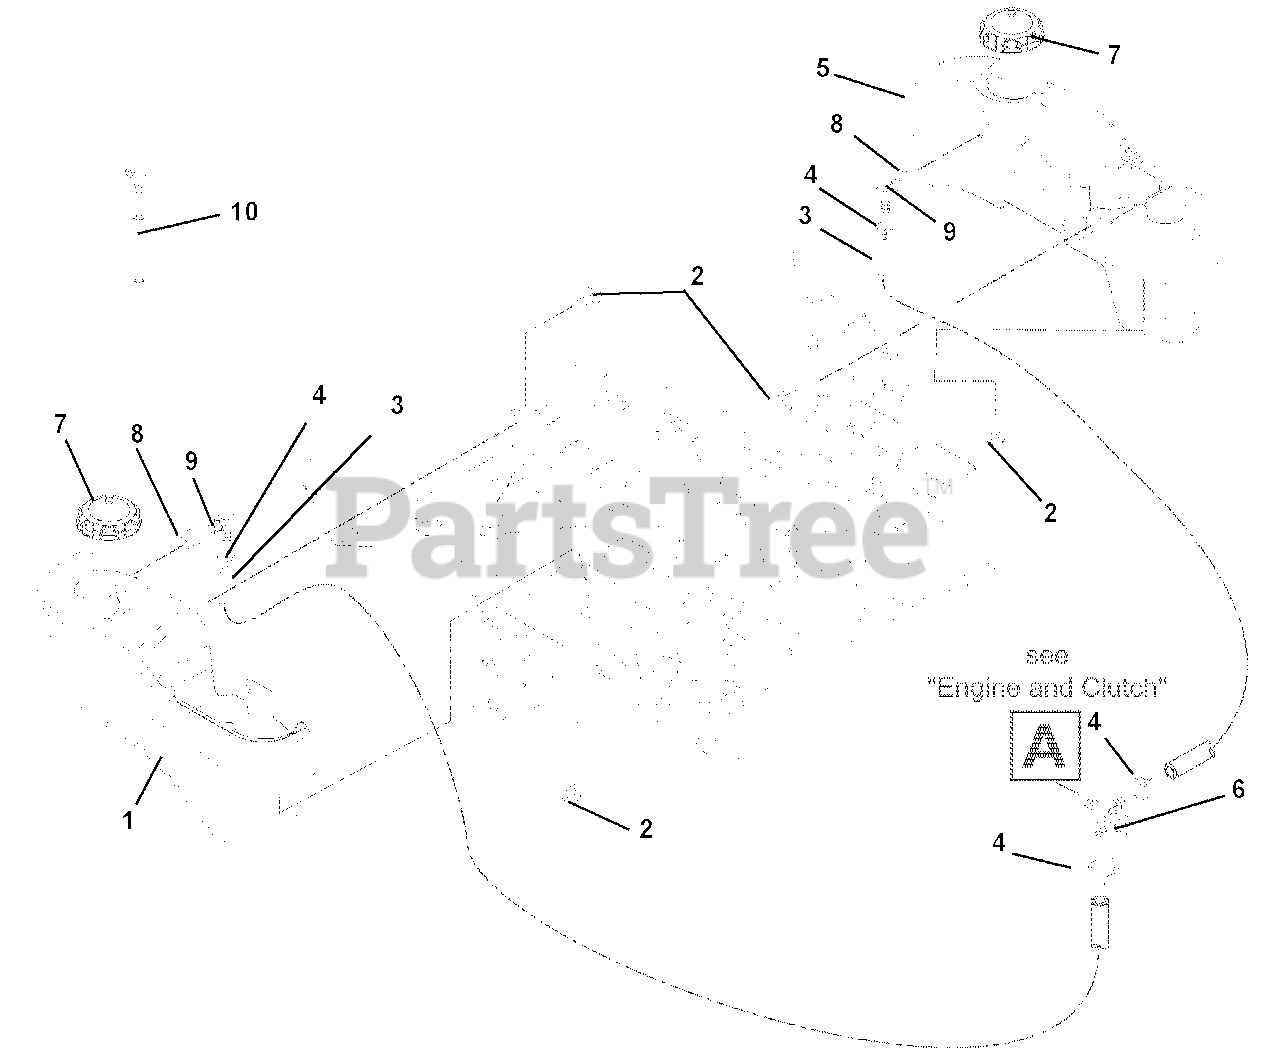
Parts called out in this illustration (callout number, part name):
1	Tank, Fuel - Right Hand
2	Bolt, SEMS .31-18 x .62
3	Gas Line, Bulk .25 I.D. (2 @ 42 in.) (992146, 147, 148, 149, 150, 151, 153, 154, 155)
4	Clamp, Hose Wire .49/.51 x .116
5	Tank, Left Hand Fuel (EYE-Q)- 200 Series
6	Valve, Fuel
7	Cap, Gas
9	Tank Fitting
10	26" Fuel Line Kit, Gas (Inside Tank)
